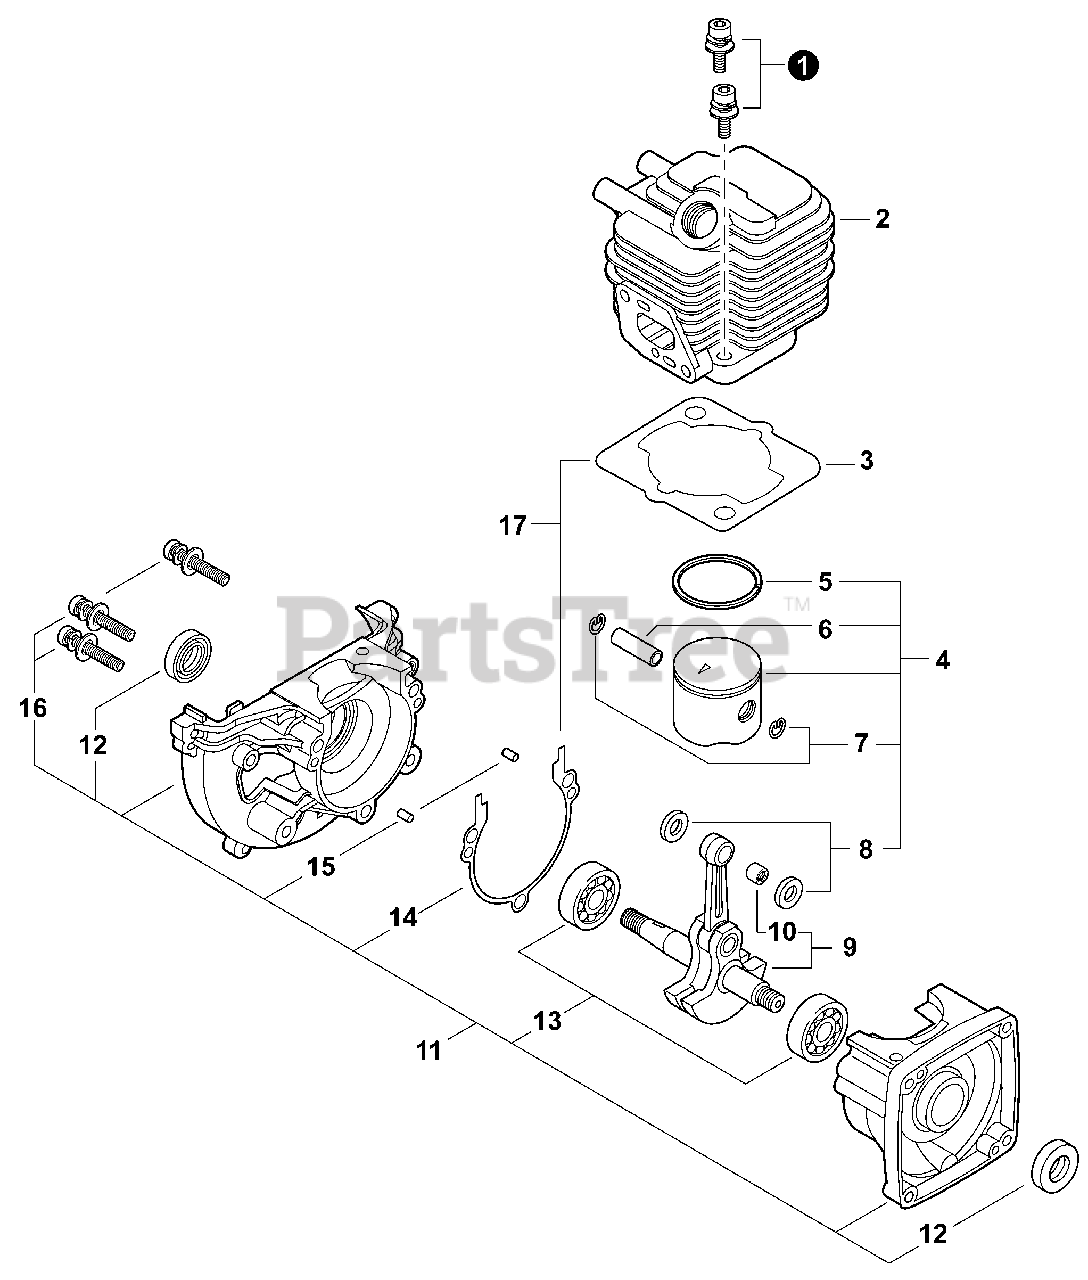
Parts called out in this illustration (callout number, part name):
1	BOLT 5×22
2	CYLINDER
3	GASKET, CYLINDER
4	PISTON KIT
5	RING, PISTON
6	PIN, PISTON 8
7	RING, SNAP
8	WASHER, THRUST
9	CRANKSHAFT ASSY
10	BEARING, NEEDLE 8
11	CRANKCASE KIT
12	SEAL, OIL 12
13	BEARING, BALL - 6201 C3
14	GASKET, CRANKCASE
15	PIN, LOCATING 4×8
16	BOLT 5×28
17	GASKET KIT: ENGINE, INTAKE, EXHAUST
